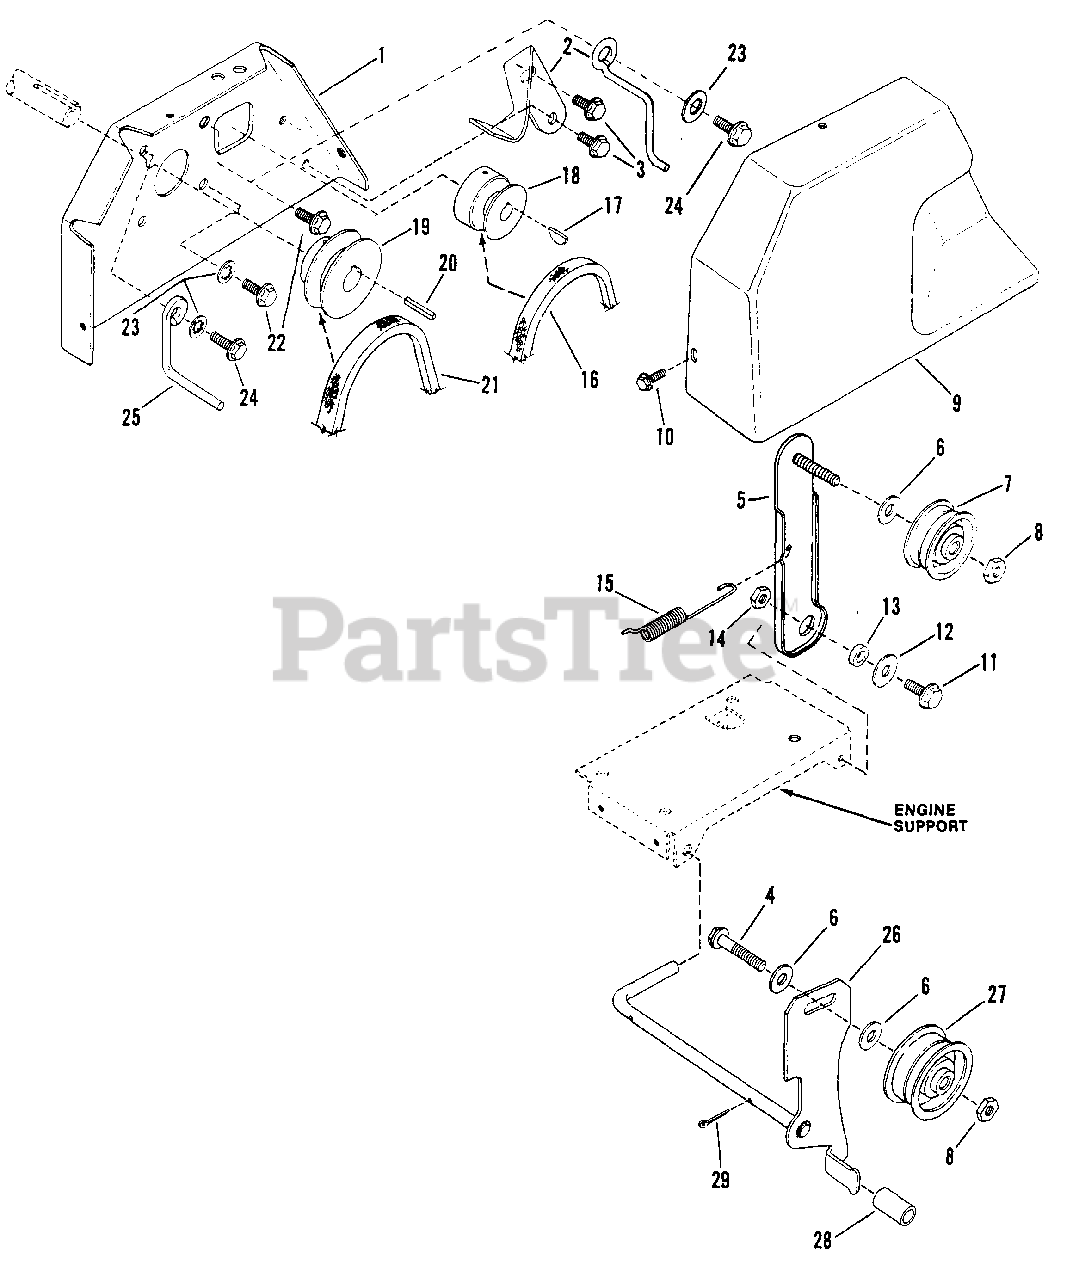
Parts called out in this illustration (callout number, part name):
1	PLATE, Engine
2	GUIDE, Belt (4 & 5 HP Models)
3	SCREW, 5/16-18x1/2" Self-Tapping
4	SCREW, 3/8-16x1-3/4", Hex Head Cap
5	BRACKET, Idler (4 & 5 HP Models)
6	WASHER, 3/8" Flat
7	IDLER
8	NUT, 3/8-16 Hex Center Lock
9	COVER, Belt
10	SCREW, #10-24 x 1/2" Hex Washer Self-Tap (Torx)
11	SCREW, 5/16-18x5/8", Hex Head Cap
12	WASHER
13	SPACER
14	NUT, 5/16-18 Hex Center Lock
15	SPRING
16	BELT, Traction (4 & 5 HP Models)
17	KEY, Woodruff
18	PULLEY, P.T.O. (4 & 5 HP Models)
19	PULLEY, Auger Drive
20	KEY, 3/16x3/16x1"
21	BELT, Blower
22	Screw, 5/16-24x1/2", Hex Head Cap
23	WASHER, 5/16 internal Tooth Lock
24	SCREW, 5/16-24x3/4" Hex Head Cap
25	FINGER, Belt
26	BRAKE ARM & ROD
27	IDLER
28	TUBE, Brake
29	COTTER PIN, 1/16X3/4" BLACK ZINC COATED.
